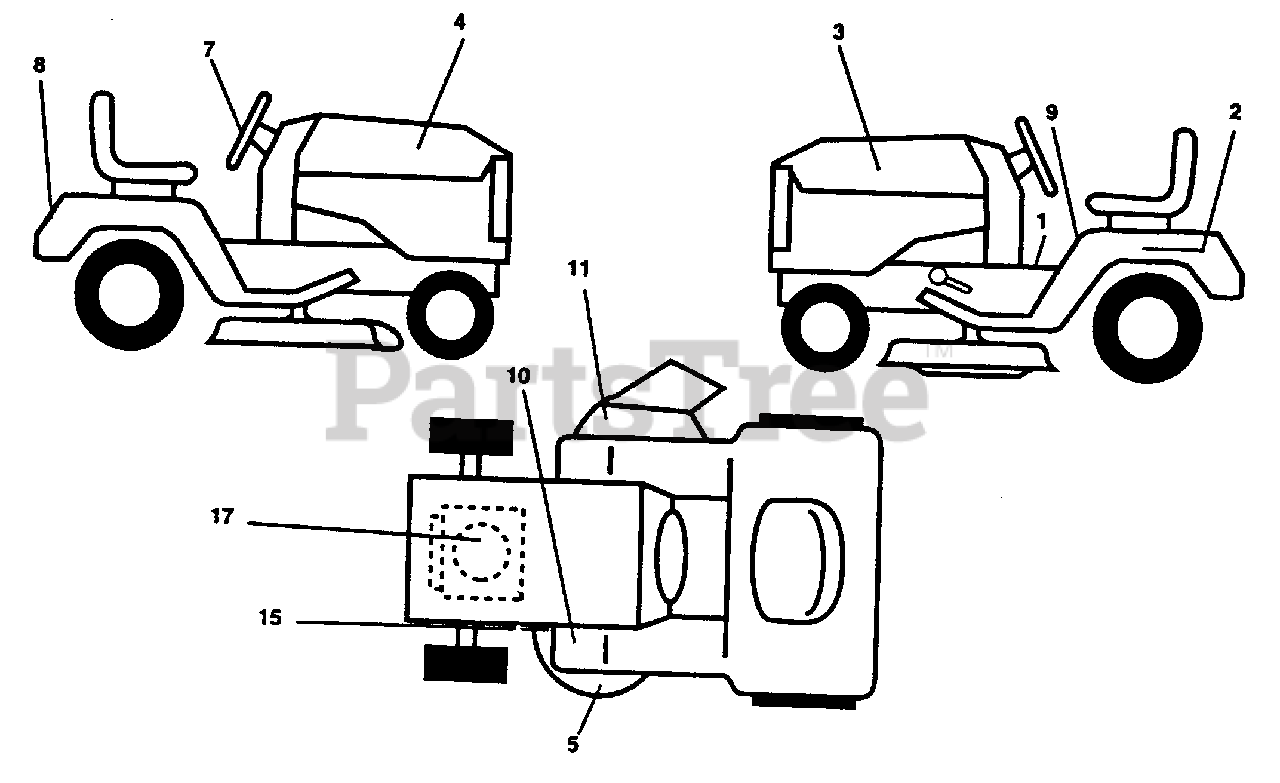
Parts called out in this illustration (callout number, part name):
1	Decal Instruction Dash Eng/fr (AYP part number)
2	Decal Caution Battery Fr/ger (AYP part number)
3	Decal Hood LH
4	Decal Hood RH
5	Decal Enviro Deck Yellow (AYP part number)
7	Decal Insert Strg Whl
8	Decal Fender Logo (AYP part number)
9	Decal Caution Fender Eng/fr (AYP part number)
10	Decal Clutch/brake Eng/fr (AYP part number)
11	Decal Warning Multi-Language (AYP part number)
15	Decal V-Belt Schematic (AYP part number)
17	Decal HP Engine (AYP part number)
